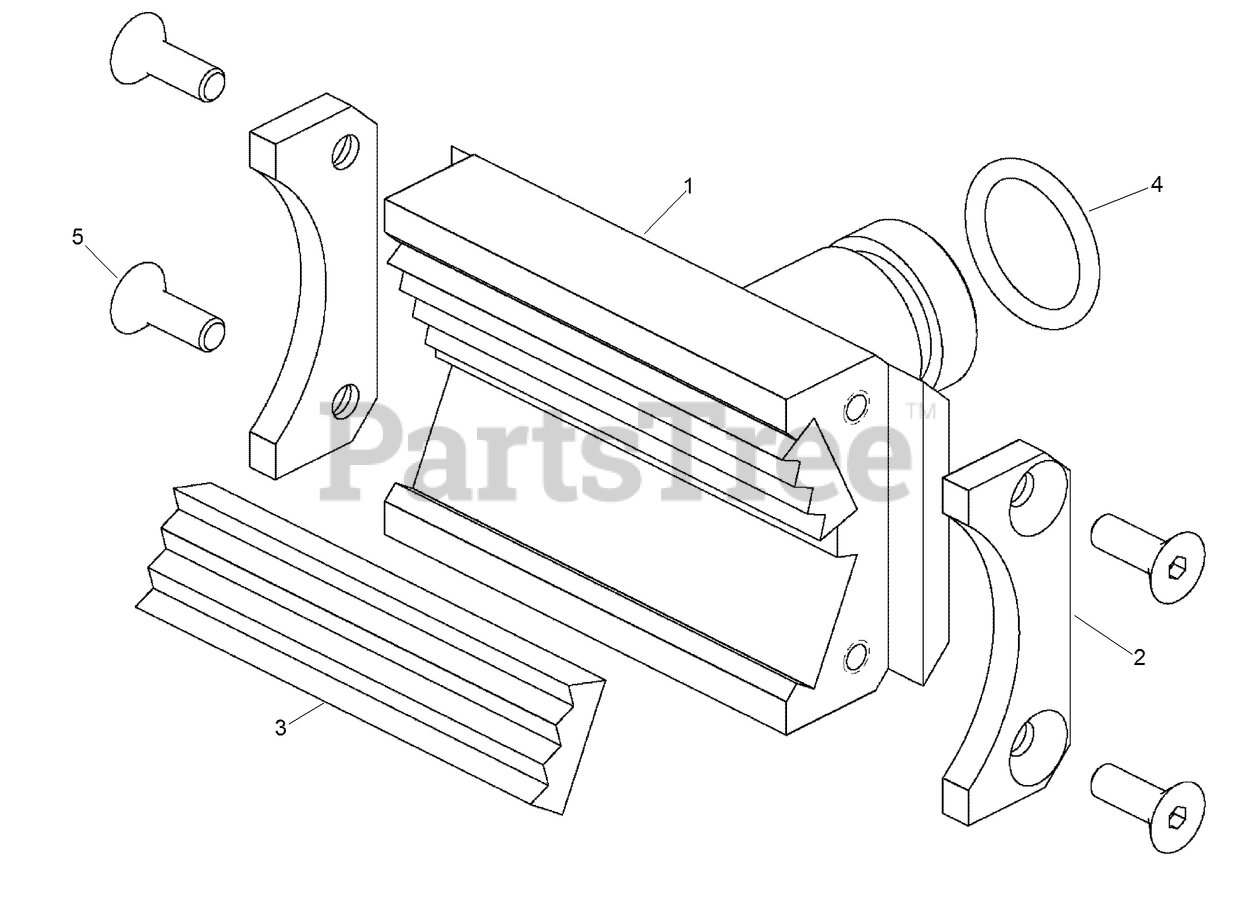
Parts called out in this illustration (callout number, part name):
1	HOLDER-DIE, FIXED
2	RETAINER-DIE
3	TONG-DIE
4	SEAL, O-RING
5	SCREW - Hex Soc Flh 1/4 UNRC x .75 ZND
